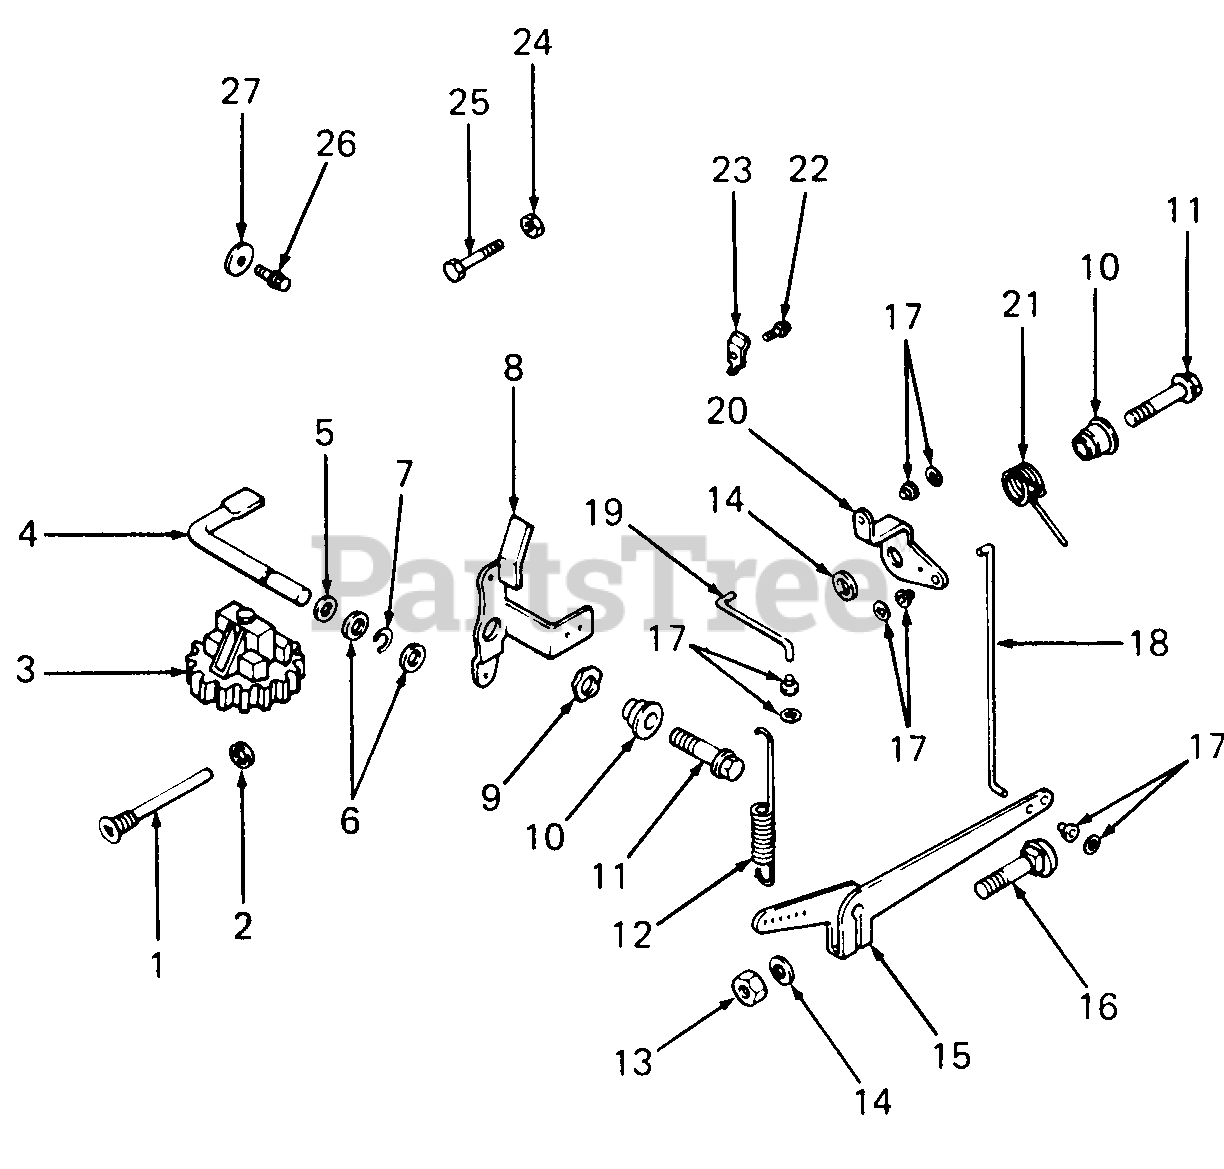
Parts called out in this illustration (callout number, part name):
1	Pin, Governor Stop
2	Washer, Plain, 1/4
3	Governor Gear Kit
4	Shaft, Governor Cross
5	Washer, Plain, 1/4
6	Washer, Plain, 1/4
7	Retainer, Governor
8	Lever, Speed Control
9	Washer, Tension
11	Screw, Hex Wash Hd, 1/4 X 20 X 1
12	Spring, Governor
13	Nut, Hex, 1/4-20
14	Washer, Plain, 1/4
15	Arm, Governor
16	Bolt, RH Sq Neck, 1/4-20 X 1
17	Bushing
18	Linkage, Governor
19	Linkage, Throttle
20	Lever, Throttle
21	Spring, Torsion
22	Screw, Hex Wash Hd, 10-24 X 3/8
24	Nut, Hex, 10-32
25	Screw, Hex Wash Hd, 10-32 X 9/16
26	Screw, Hex Wash Hd, 10-32 X 9/16
27	Washer, Plain, 1/4
